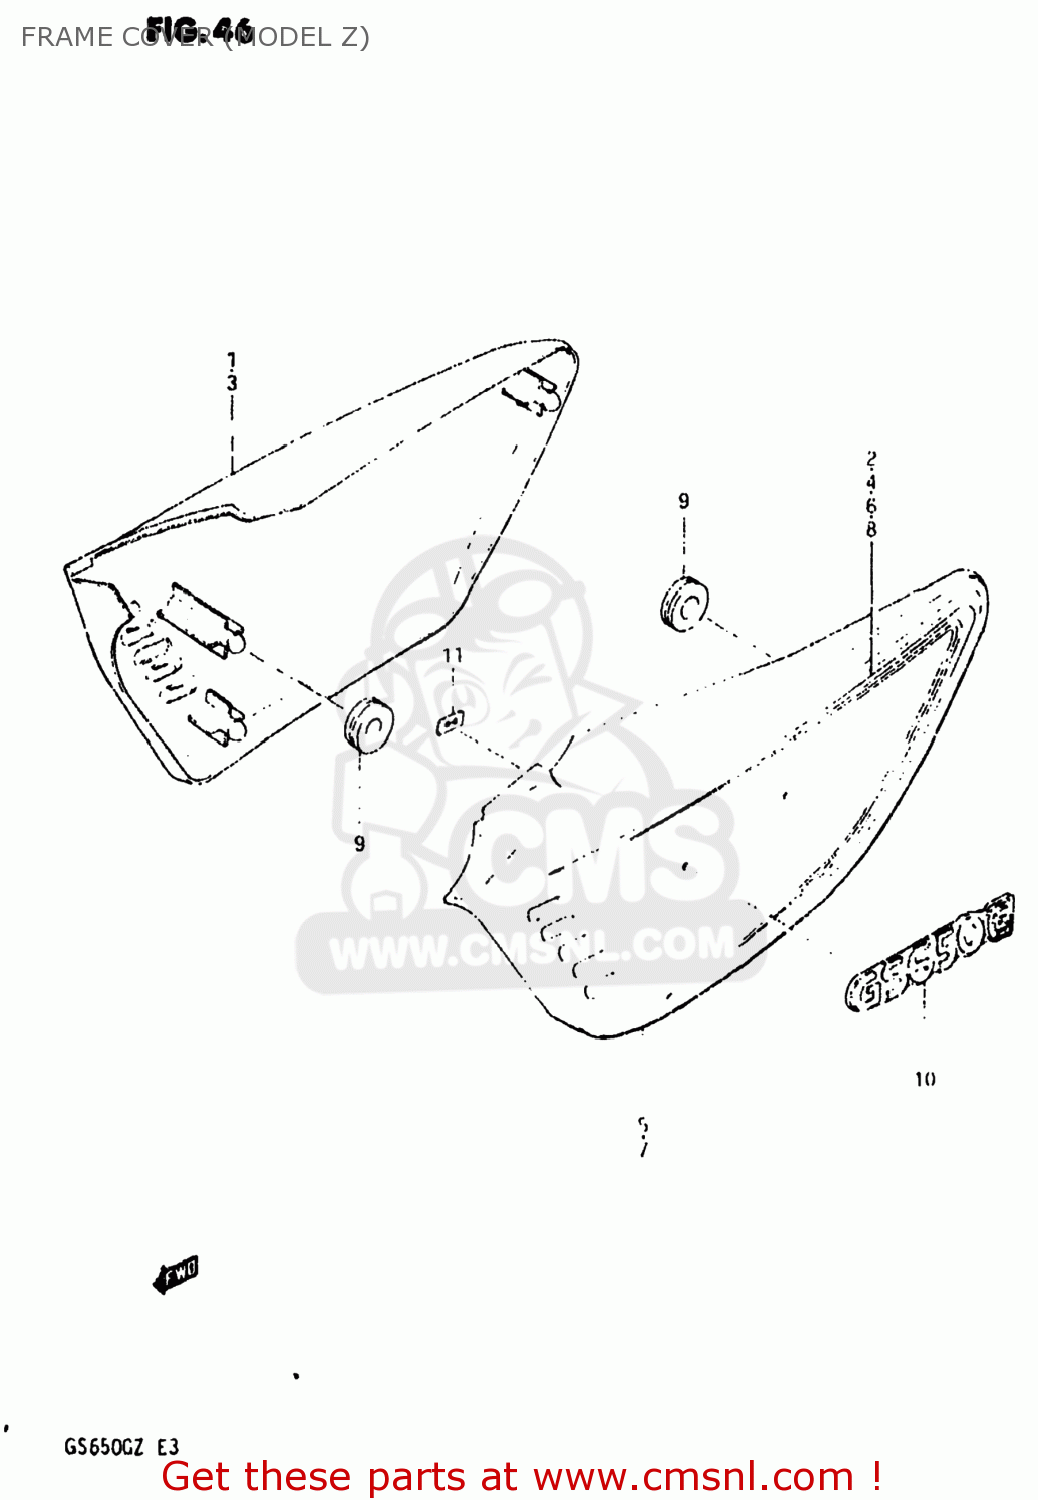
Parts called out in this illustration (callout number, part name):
1	COVER,FRAME,RIGHT
2	TAPE,FRAME COVER,RIGHT
3	COVER,FRAME,RIGHT
4	TAPE,FRAME COVER
5	COVER,FRAME,LEFT
6	TAPE,FRAME COVER
7	COVER,FRAME,LEFT
8	TAPE,FRAME COVER
9	CUSHION
10	EMBLEM,FRAME COVER
11	NUT
